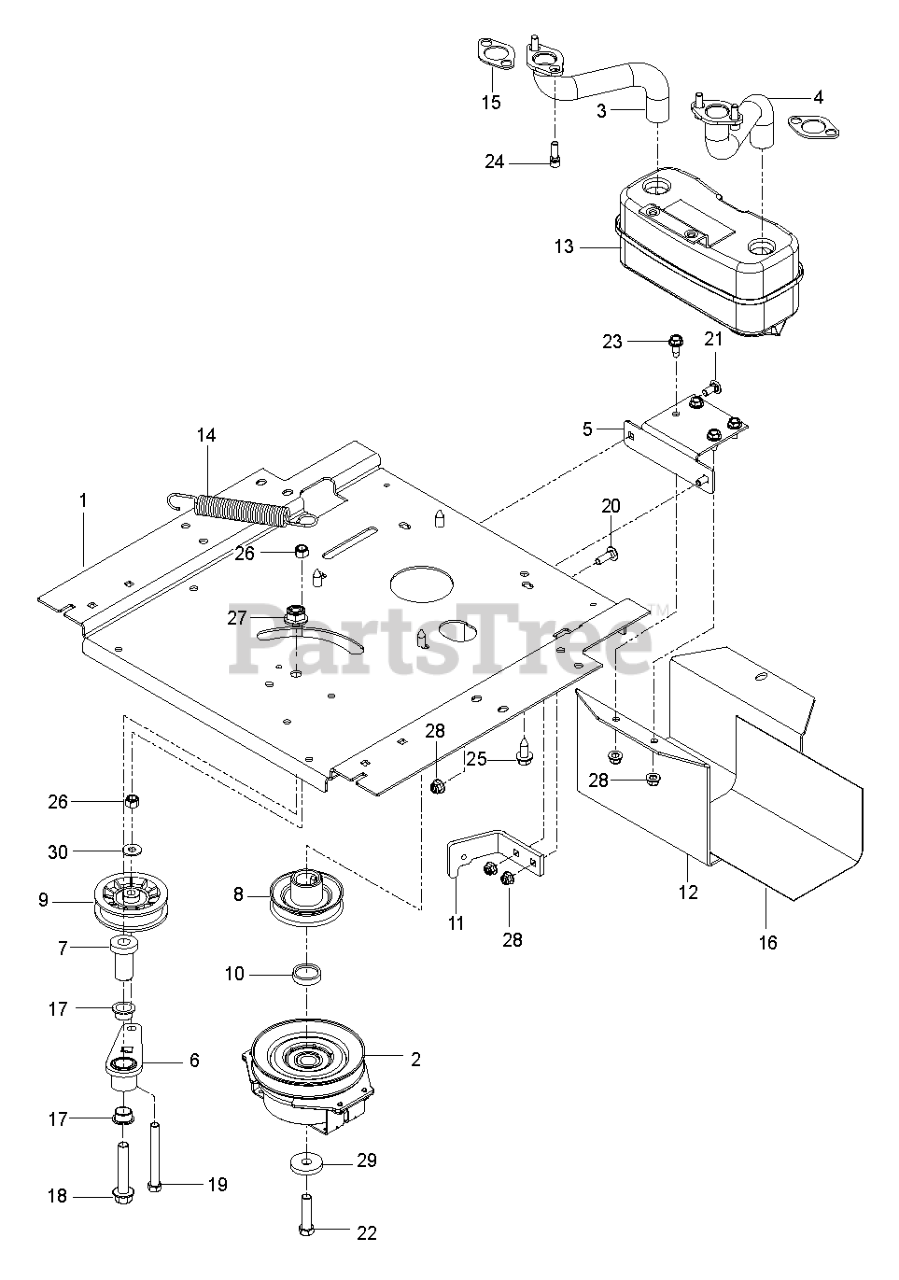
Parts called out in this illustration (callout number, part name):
563	Screws
564	Screws
564B	Screws
604C	Covers
969	Screws
969A	Screws
